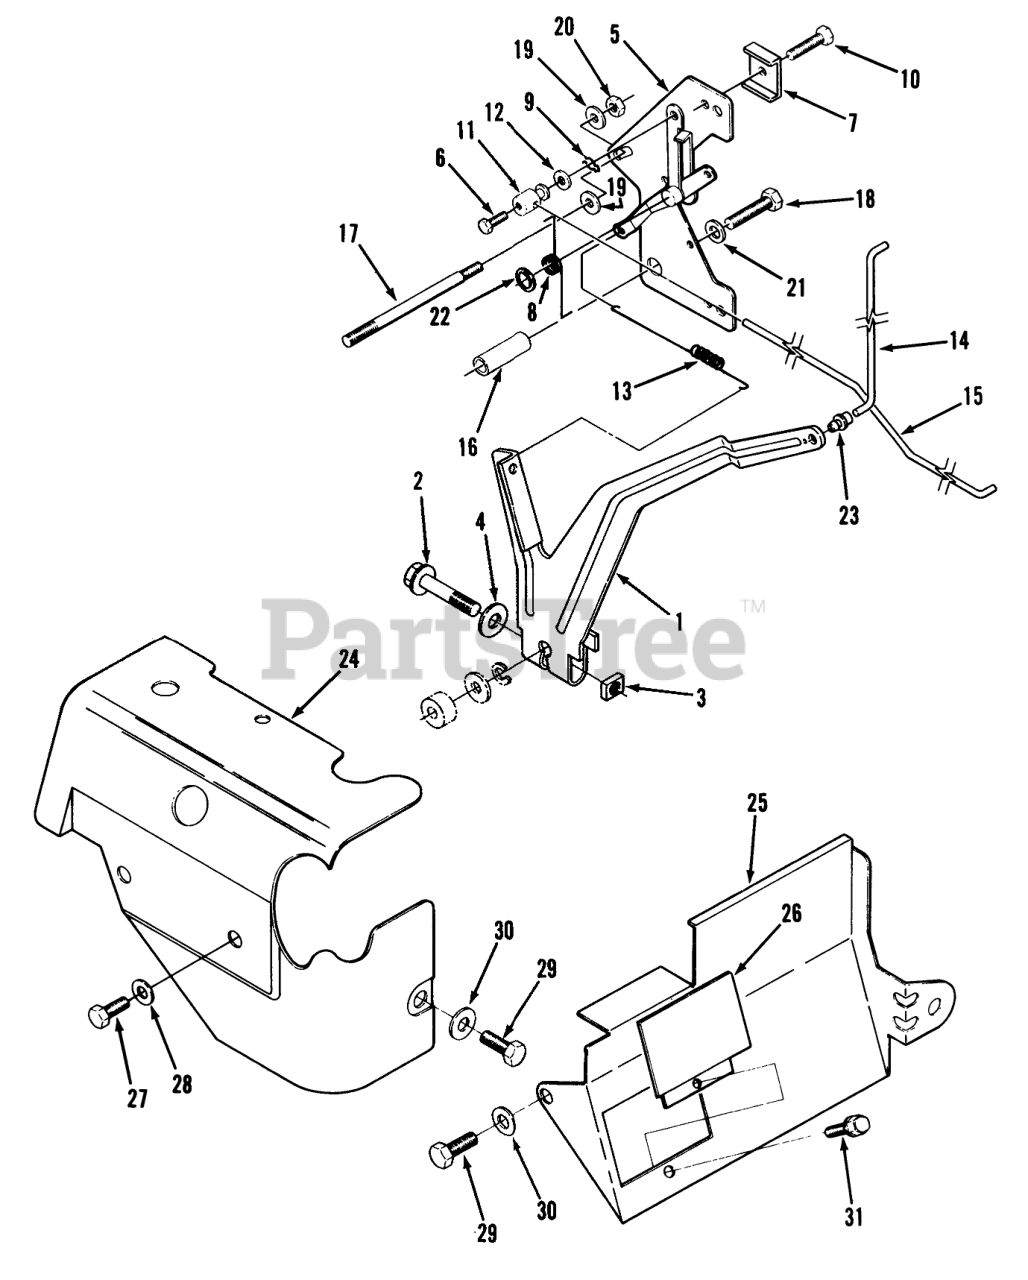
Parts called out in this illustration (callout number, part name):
1	LEVER-GOVERNOR
2	HHCS-M8 X 35MM
3	Nut
4	Washer
5	Throtte Plate Assembly (Includes Control and Choke Levers, Pivot Pin and Flat Washers)
6	HHMS #8-32X3/8"
7	Plug-Pipe
8	SPRING-CHOKE LINKAGE
9	Cotler Pin
10	HWHTF-SCRW M5X12MM
11	SWIVEL-CHOKE LEVER
12	Washer
13	SPRING-GOVERNOR
14	LINK-THROTTLE
15	LINK-CHOKE
16	SPACER
18	HHCS-M8 X 40MM
19	Washer
20	NUT-HEX M6
21	Nut-M8
22	RING-RETAINER
23	Clip-Link
24	HSG-CYL AIR
25	Air Deflector
26	Cover
27	HHCS-M6 X 10MM
28	Washer
29	HHCS-M8 X 10MM
30	Nut-M8
31	Bolt
